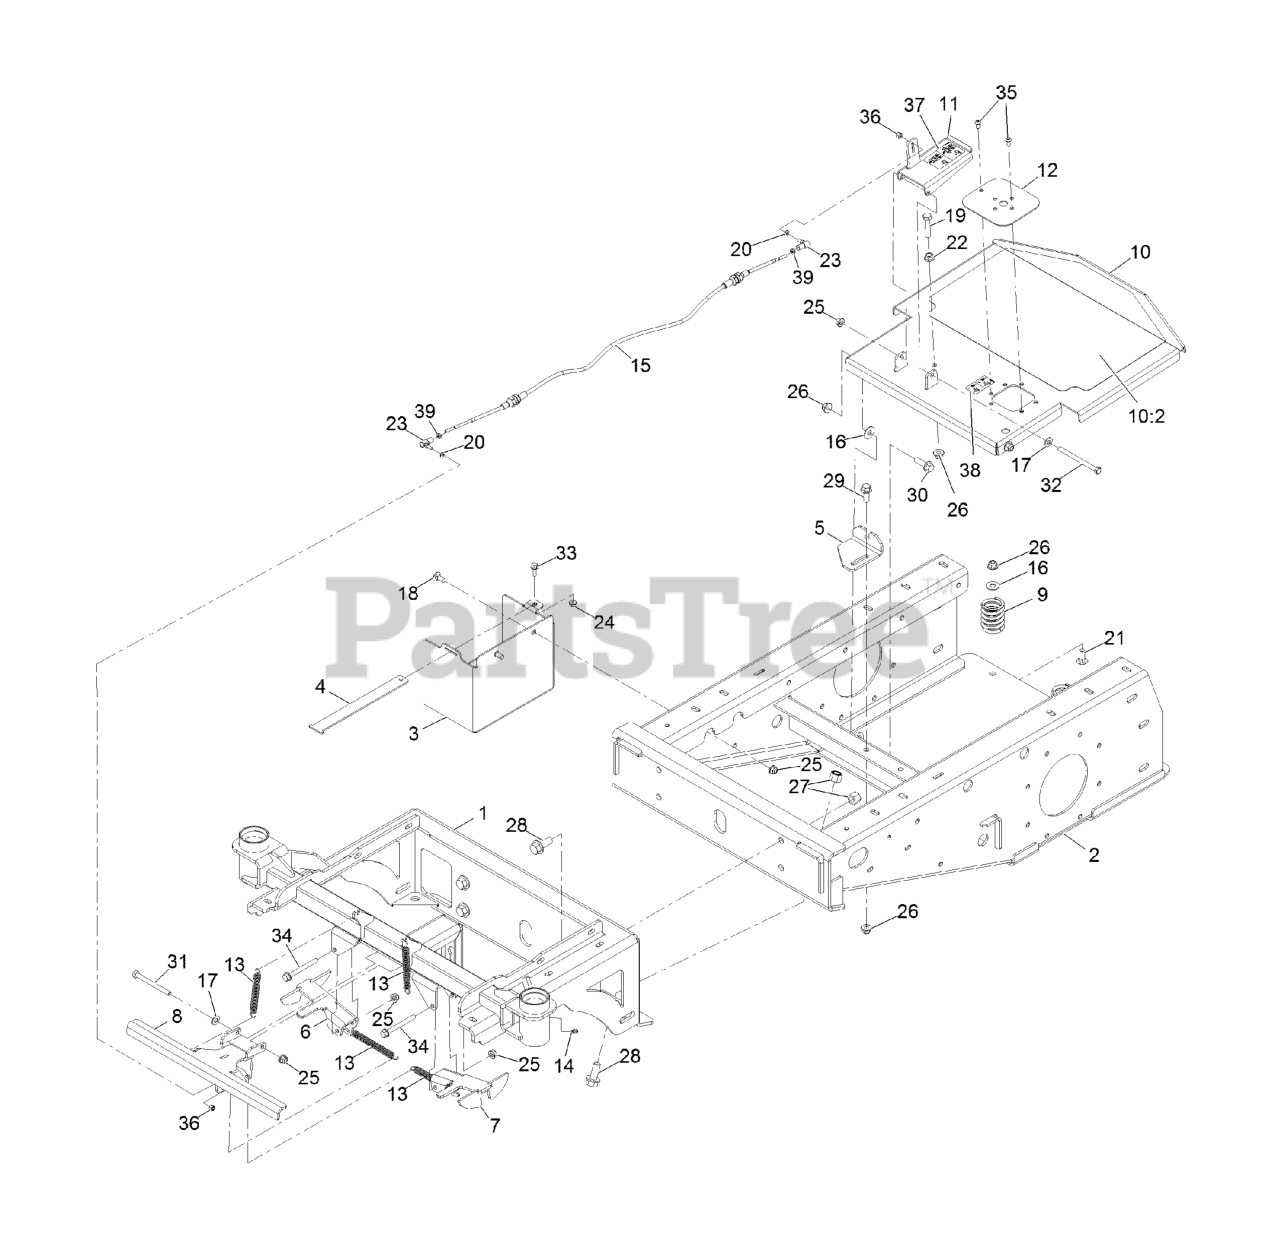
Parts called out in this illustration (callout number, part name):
1	Frame-Front
2	FRAME-REAR
3	Box-Battery
4	STRAP-BATTERY
5	Bracket, Lower Cable
6	Wing-Capture, Rt
7	Wing-Capture, Lt
8	Capture-Lcs
9	SPRING-COMPRESSION
10	Plate-Foot
10:2	PAD-GRIP
11	Pedal-Foot
12	Panel, Foot Switch
13	SPRING-EXTENSION
14	FITTING-GREASE, ZERK
15	CABLE-CASTER, LOCKING
16	WASHER-FLAT
18	SCREW-CARR
19	Screw-HH
20	WASHER-FLAT
21	SCREW-CARR
22	Nut-Hex Flange
23	BALL JOINT-SS
24	Nut-Hex Flange
25	Nut-Hex Flange
26	Nut-Hex Flange
27	Nut,1/2-13,NYL INS,ST/ST,18-8
28	SCREW-HHF
29	SCREW-HHF
30	SCREW-HHF
31	SCREW-HH
32	Screw-HH
33	Screw-HHF
34	SCREW-HHF
35	Screw-HSBH
36	Nut,NYL Lock,#10-32,ST/ST 18-8
37	Decal-Lock, Caster
38	Decal-Spray Foot Button
39	Nut,Hex Jam Mch Scr,10-32,Sst
